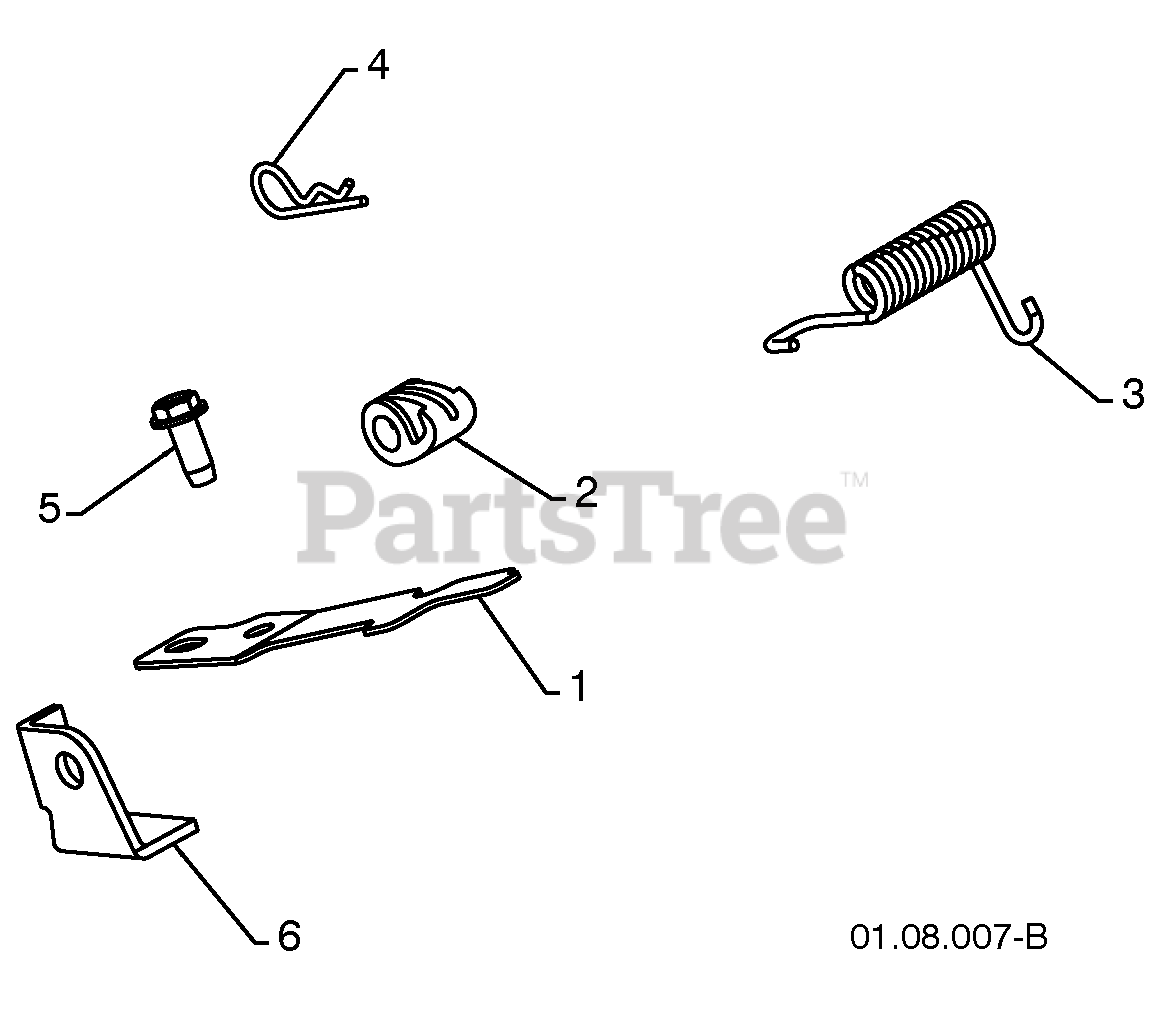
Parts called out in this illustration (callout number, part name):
1	INTERLOCK SPRING
2	INTERLOCK CAM
3	TORSION SPRING
4	RETAINER
5	SCREW 1/4-20 X .625
6	INTERLOCK STOP
